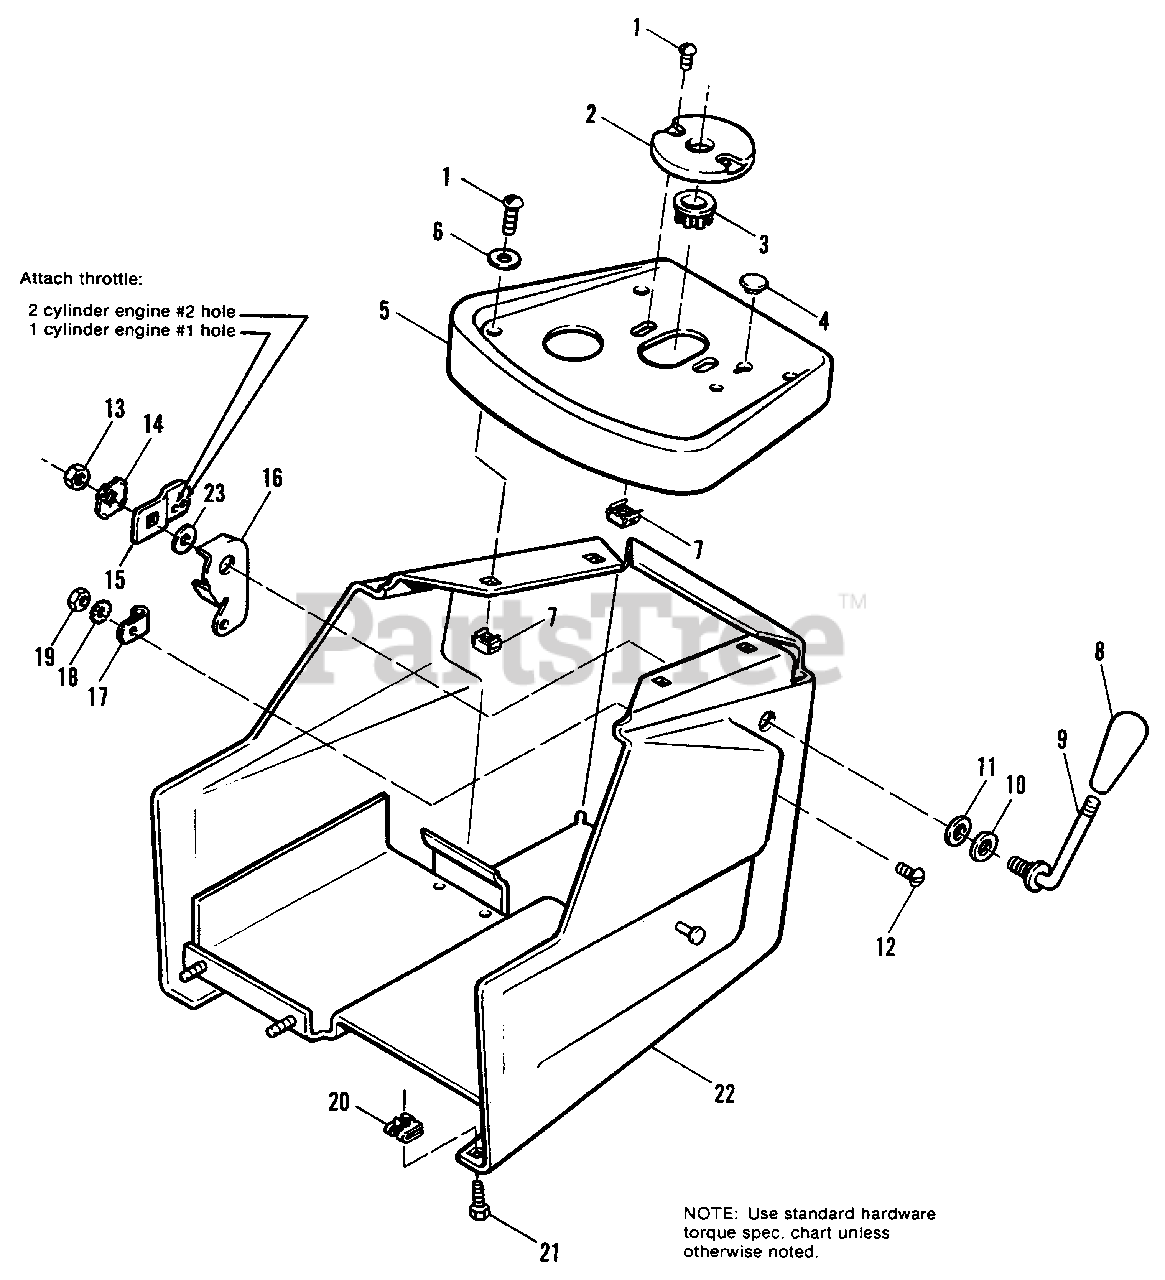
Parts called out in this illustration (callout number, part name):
1	SCREW, Rd. Hd., 1/4-20 x 1/2
2	PLATE, Steering
4	BUTTON, Plug
5	PANEL, Instrument
6	WASHER, Plain, 3/16
7	NUT, Tinnerman
8	KNOB, Tapered
9	HANDLE, Clutch Control
12	SCREW, Rd. Hd., #10-32 x 1/2
13	LOCKNUT, Hex, 3/8-16
14	LOCKWASHER, Dished Type Shakeproof, 3/8
15	ARM, Throttle
16	STOP, Throttle
17	CLIP, Bowden Wire
18	LOCKWASHER, External, #10
19	NUT, Hex, #10-32
20	NUT, Speed, Tinnerman
21	SCREW, Hex Hd., #14 x 3/4
23	WASHER, Nylon
